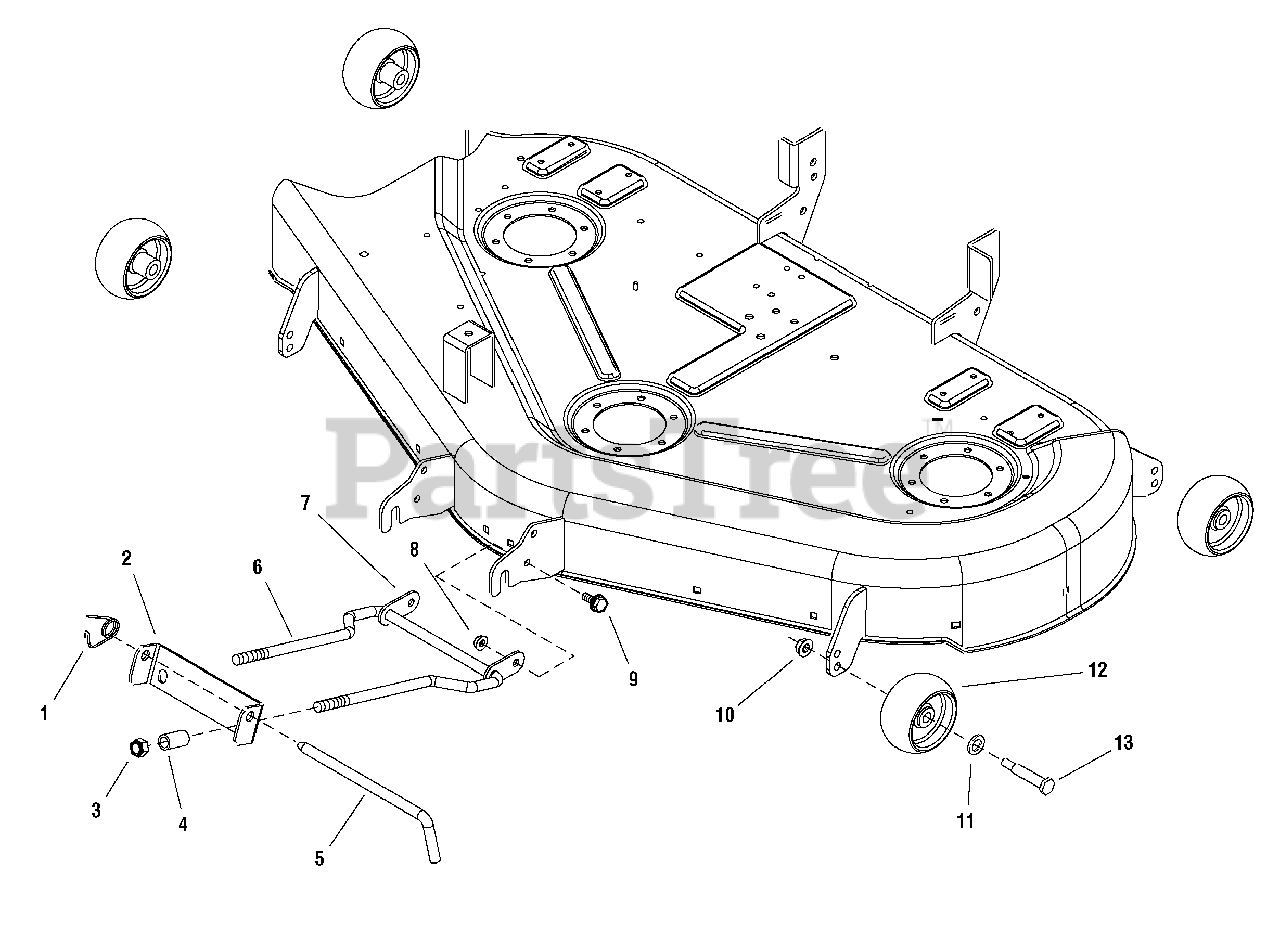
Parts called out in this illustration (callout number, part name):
1	CLIP, Pin, Safety
2	HANGER, Front Mower
3	NUT, Hex Lock, 1/2-13
4	SPACER, 1/2 x 7/8 x 1 3/16
5	PIN, Hitch
6	ROD, Bail Mowers Yellow
7	PLATE, PIVOT Lock 10 GA
8	NUT, Hex, Flange Whizlock, 5/16-18
9	CAPSCREW, Hex Head, Flange Whiz Lock, 5/16-18 x 3/4
10	NUT, Hex Flange, 3/8-16 ESNA
11	WASHER, 1/2
12	WHEEL, Gauge
13	BOLT, Rear Wheel
